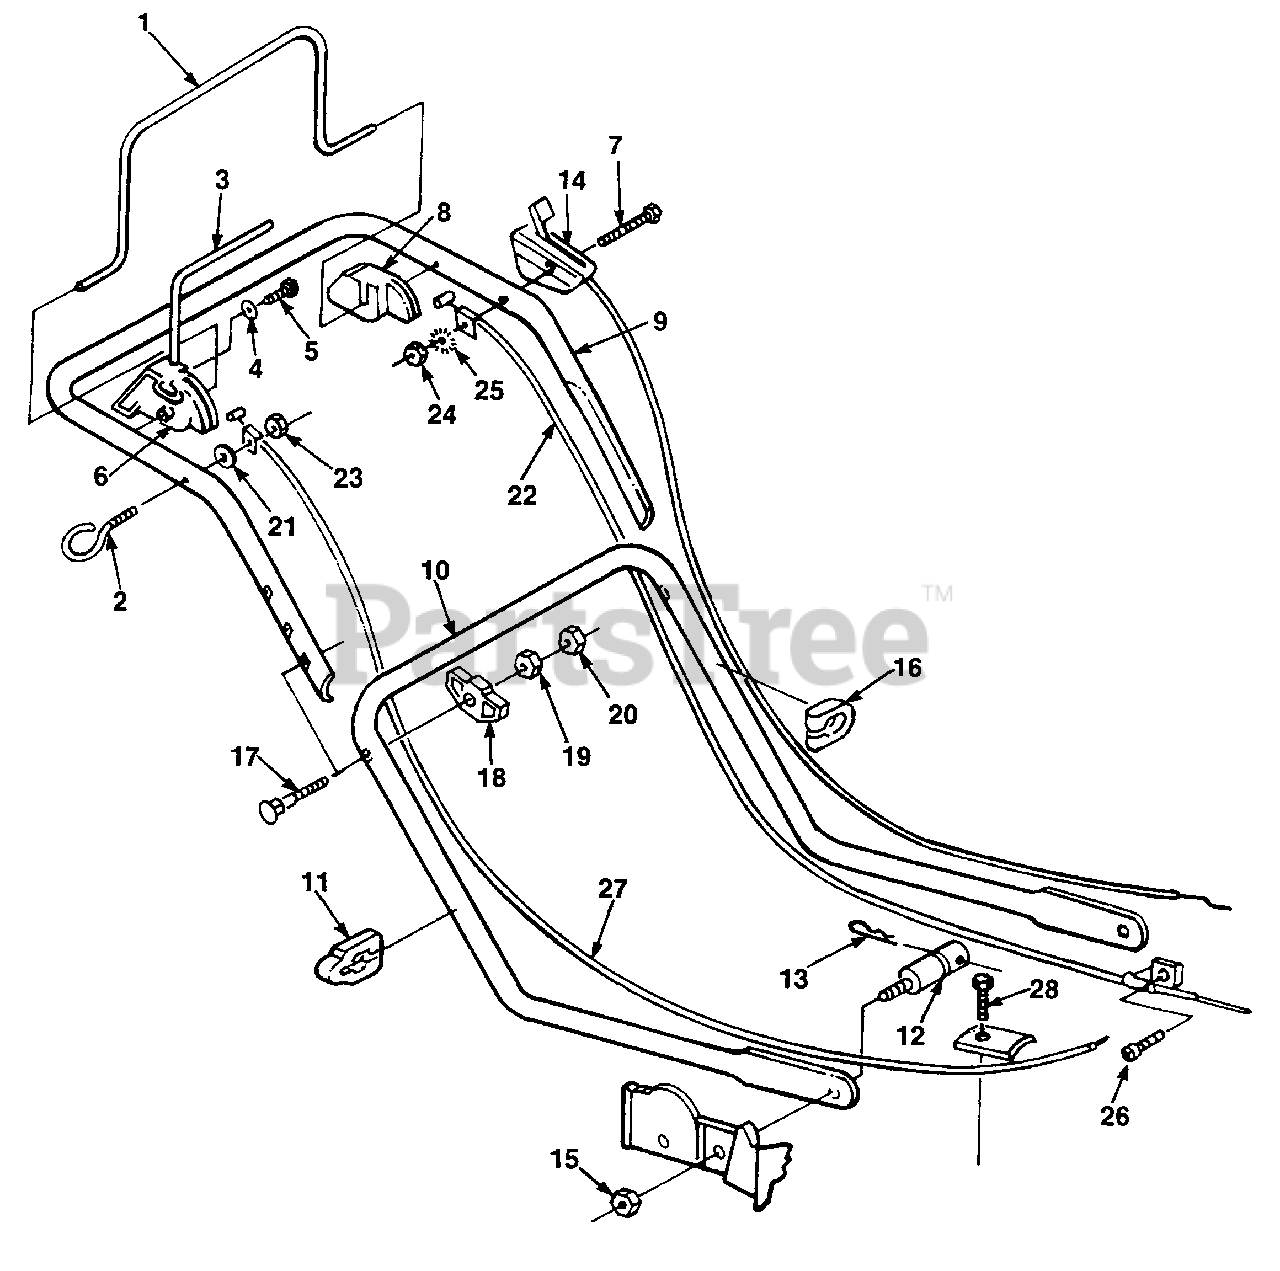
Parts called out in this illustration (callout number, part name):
1	BAIL- Brake
3	TRACTION BAIL
4	WASHER
5	SCREW
6	ACTUATOR- R.H.
7	BOLT- Sq. neck
8	ACTUATOR- L.H.
9	HANDLE- Upper
10	HANDLE- Lower
11	CLAMP- Cable (single)
12	STUD- Handle mtg.
13	PIN- Cotter hair
14	CONTROL- Throttle
15	NUT- Hex flange 5/16-18
16	CLAMP- Cable (double)
17	BOLT- Sq. neck
18	KNOB- Handle
19	NUT- Hex locking 5/16-18
20	NUT- Hex locking 5/16-18
22	CONTROL- Manual start
23	NUT- Hex locking 1/4-20
24	NUT- Hex
26	SCREW- Hex hd. (10-32 x 3/8")
27	CABLE- Traction
28	SCREW- Hex hd. (1/4-20 x 5/8")
